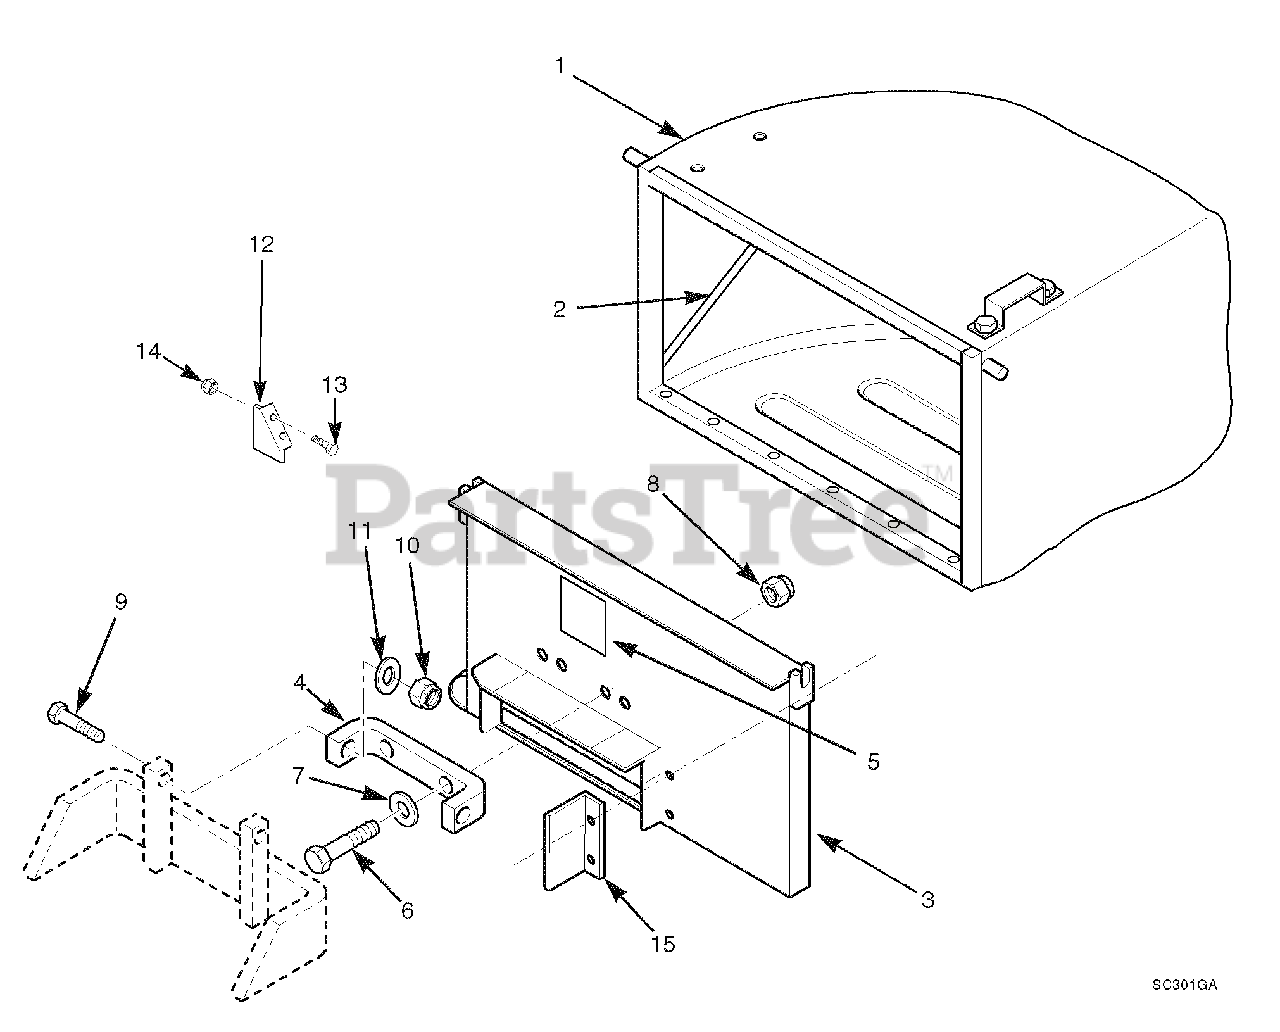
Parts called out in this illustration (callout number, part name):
1	Catcher Bag
2	Frame Weldment With Catcher Bag and Handle Assembly
3	Cover Weldment With Decal
4	Bracket, Mounting
5	Decal, Danger
6	Bolt, 3/8-16 x 1-1/2" Hex Head
7	Flat Washer, 3/8"
8	Nut, 3/8-16 Elastic Stop
9	Bolt, 5/16-18 x 1-1/4" Hex Head
10	Nut, 5/16-18 Elastic Stop
11	Flat Washer, 5/16"
12	Filler Plate, Chute Advantage Deck Only
13	Bolt, Hex Head 1/4-20 x 3/4"
14	Nut, Elastic Stop 1/4-20
15	Filler Plate, Grass Catcher Advantage Decks
